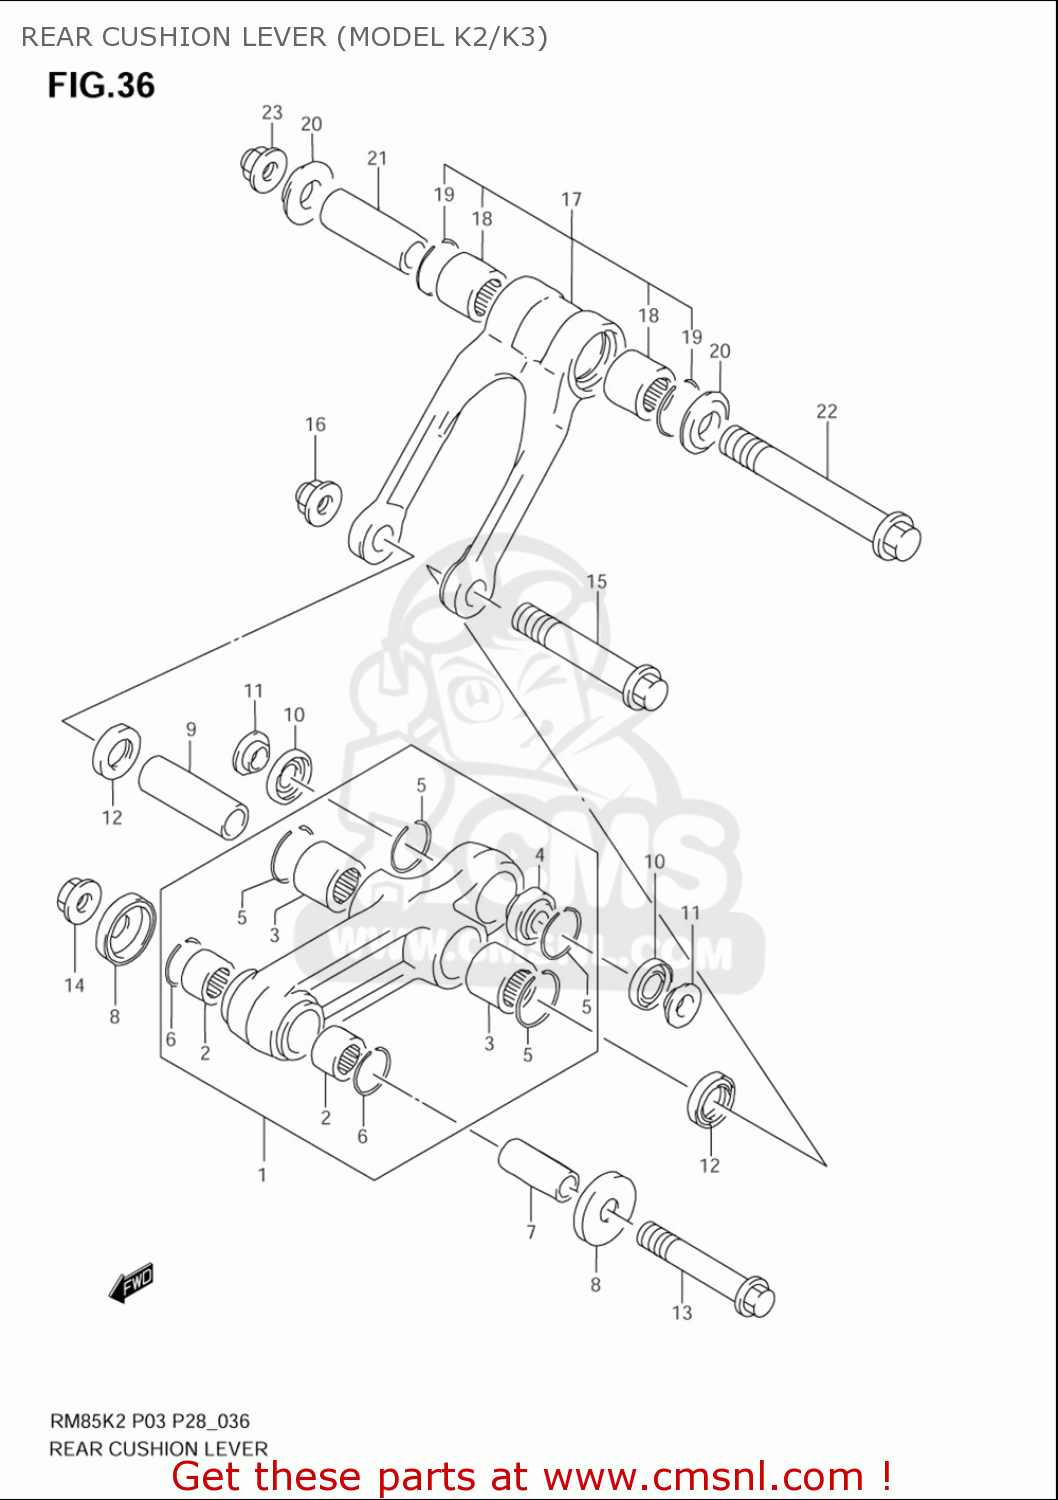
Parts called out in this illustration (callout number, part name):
1	LEVER SET,RR CUSHION
2	BEARING(14X20X12)
3	BEARING(17X24X20)
4	BEARING,RR CUSHION LEVER
5	RING,STOPPER
6	CIRCLIP,PISTON PIN
7	SPACER,RR CUSHION LEVER FR
8	SEAL,RR CUSHION LEVER FR DUST
9	SPACER,RR CUSHION LEVER CTR
10	SEAL,RR CUSHION LEVER RR DUST
11	SPACER,RR CUSHION LEVER RR
12	SEAL,OIL(17X24X3)
13	BOLT,RR CUSHION LEVER FR
14	NUT
15	BOLT,RR CUSHION LEVER CTR
16	NUT 12MM
17	ROD SET,RR CUSHION LEVER
18	BEARING(17X24X20)
19	RING,STOPPER
20	SPACER,RR CUSHION ROD SIDE
21	SPACER,RR CUSHION ROD
22	BOLT,RR CUSHION ROD
23	NUT 12MM
